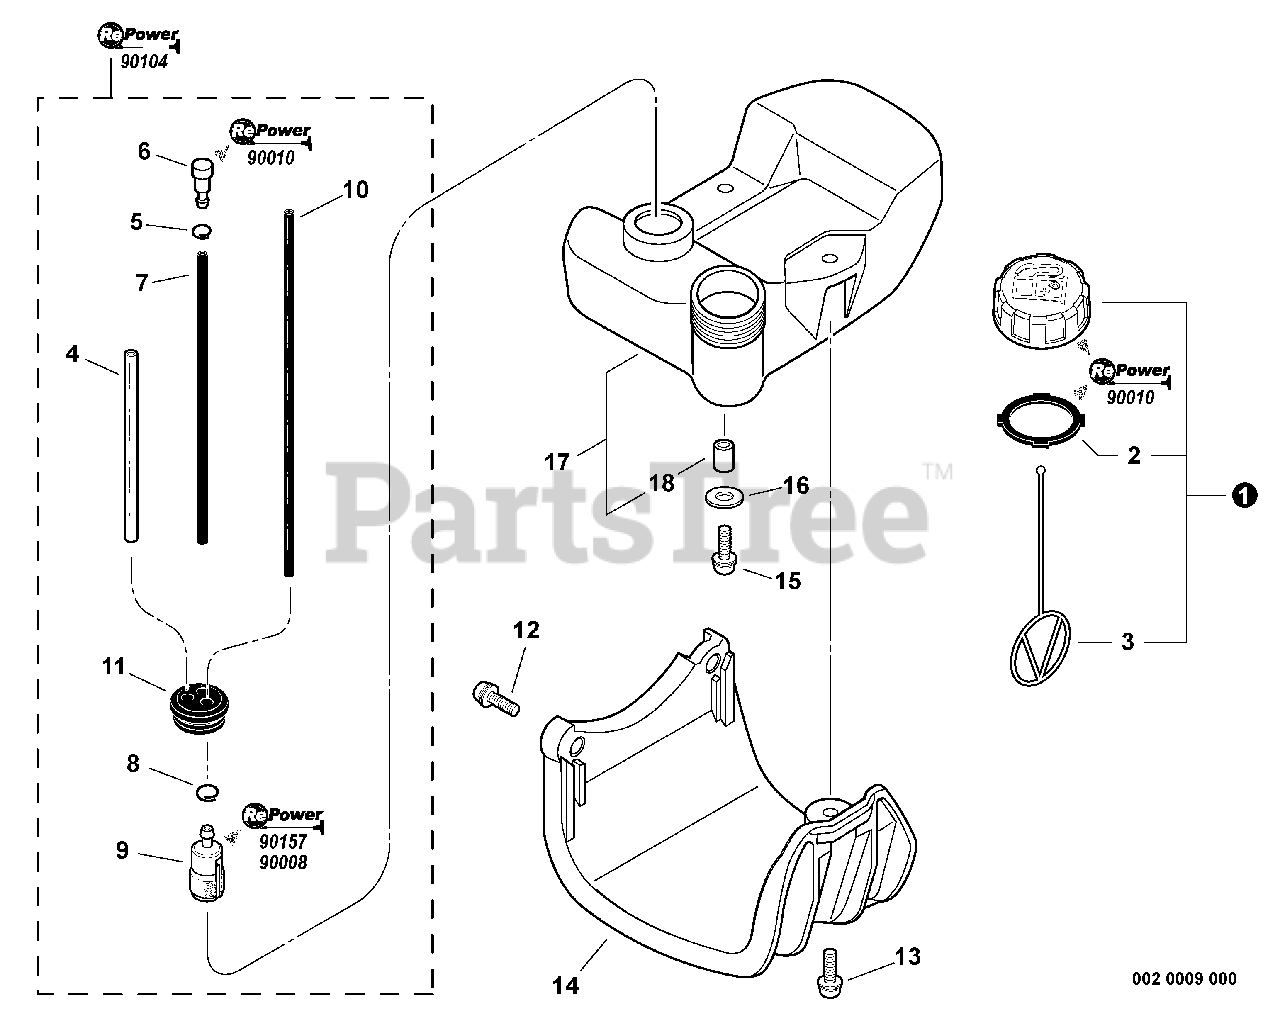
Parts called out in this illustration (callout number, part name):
1	CAP ASSY - ORANGE
2	GASKET, CAP
3	CONNECTOR, CAP
4	PIPE - 3X6X80 -- CLEAR
5	CLIP - 6.5
6	VENT, FUEL TANK
7	PIPE - 3X6X115 -- BLACK
8	CLIP - 6.5
9	FILTER, FUEL
10	PIPE - 3X6X170 -- BLACK
11	GROMMET
12	SCREW - 5X22
13	SCREW - 5X20
14	GUARD, FUEL TANK
15	SCREW - 5X16
16	WASHER - 5
17	FUEL TANK ASSY
19	RePower FILTER KIT
20	Repower CAP AND VENT KIT
21	RePower FUEL SYSTEM KIT
22	RePower TUNE-UP KIT
